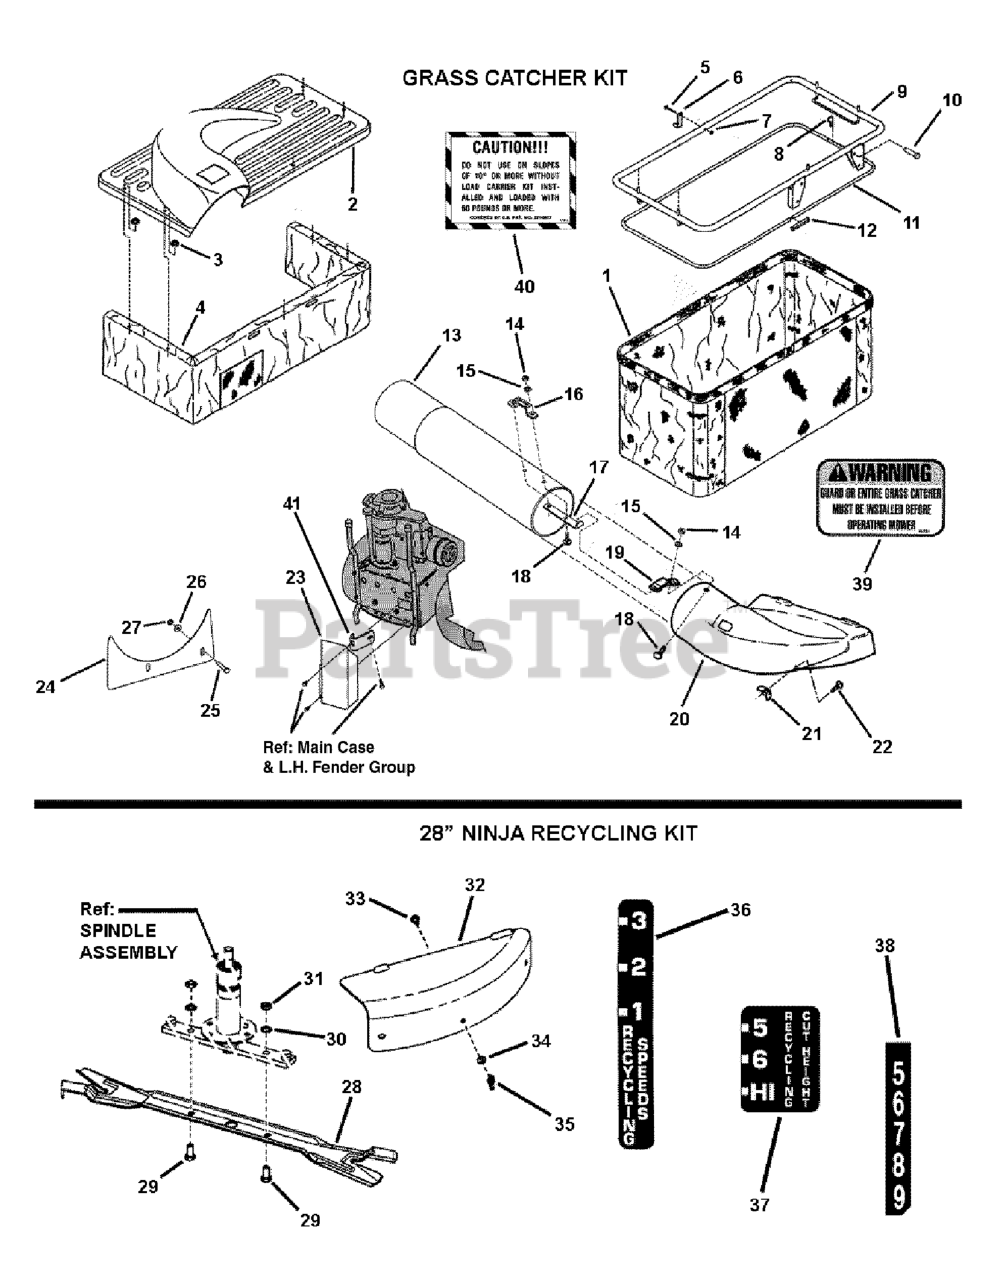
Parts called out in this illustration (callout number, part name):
1	GRASS BAG, Single, Zipperless
2	TOP, Grass Container, No Graphics
3	WASHER, 5/16 Faceted
4	DUST SKIRT
5	SCREW, #10-32 x 1-3/8" Hex Head Machine
6	LATCH, Grass Catcher Top
7	NUT, #10-32 Hex Nyloc
8	PIN, 3/32 x 1-1/2" Hair, YZ
9	FRAME STRUCTURE
10	PIN, 5/16 x 1-11/16" Clevis
11	ROD, Bag
12	CONNECTOR, Bag Rod
13	GRASS TUBE, 28-33
14	NUT, 1/4-20 Hex, YZ
15	WASHER, 1/4" Internal Tooth Lock, YZ
16	HANDLE, Tube
17	BASE, Handle
18	BOLT, 1/4-20 x 3/4" Round Head Short Square Neck Carriage, YZ
19	LATCH, Tube
20	ADAPTER, 28" Deck
21	WING LOCKNUT, 5/16-18, YZ
22	BOLT, 5/16-18 x 1" Round Head Short Square Neck, GR 5
23	MUFFLER GUARD, Grass Catcher
24	SHIELD, Grass Catcher Debris
25	BOLT, 1/4-20 x 1-1/2" Hex Head
26	WASHER, 1/4" Flat
27	NUT, 1/4-20 Hex top Lock
28	BLADE, Ninja, 28"
29	SCREW, 1/2-20 x 1" Hex Head Cap, GR 5
30	WASHER, 1/2" Internal Tooth Lock
31	NUT, 1/2-20 Hex Jam, GR 5 or B
32	COVER, 28" Mulcher
33	BOLT, 5/16-18 x 3/4" Round Head Short Square Neck Carriage, GR 5
34	WASHER, 5/16" Flat
35	NUT, 5/16-18 Wing
36	DECAL, Ground Speed, Recycle
37	DECAL, Height-Of-Cut, Recycle
38	DECAL, Height-Of-Cut
39	DECAL, Chute/Deflector Warning
40	DECAL, Grass Catcher
41	BRACKET, Bumper Reinforcement
